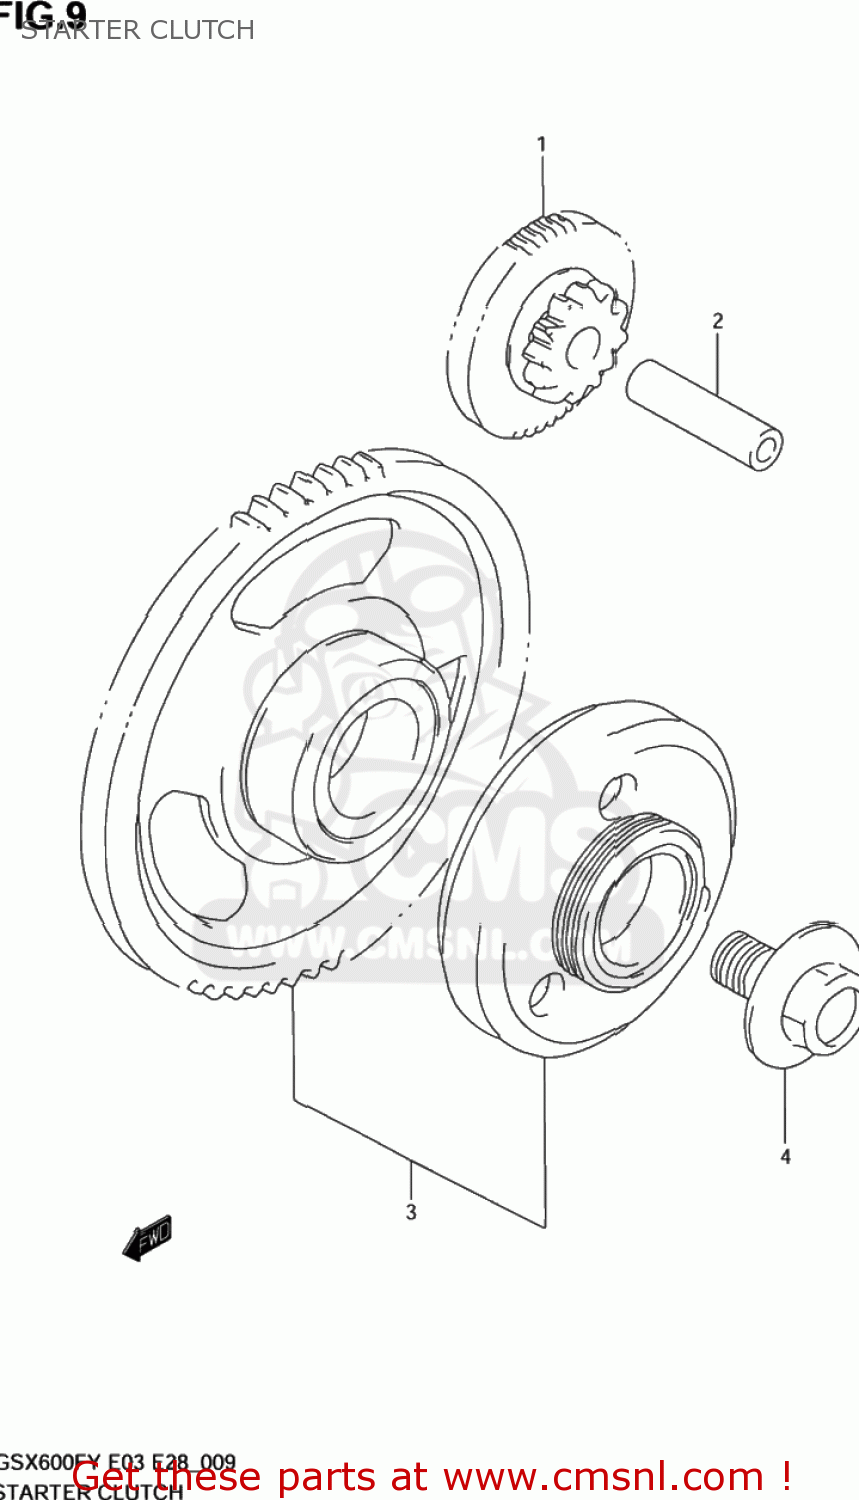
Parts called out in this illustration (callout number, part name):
1	GEAR,STARTER IDLE(NT:12,53)
2	PIN(7X11X42)
3	CLUTCH SET,STARTER
4	BOLT(14X21)
